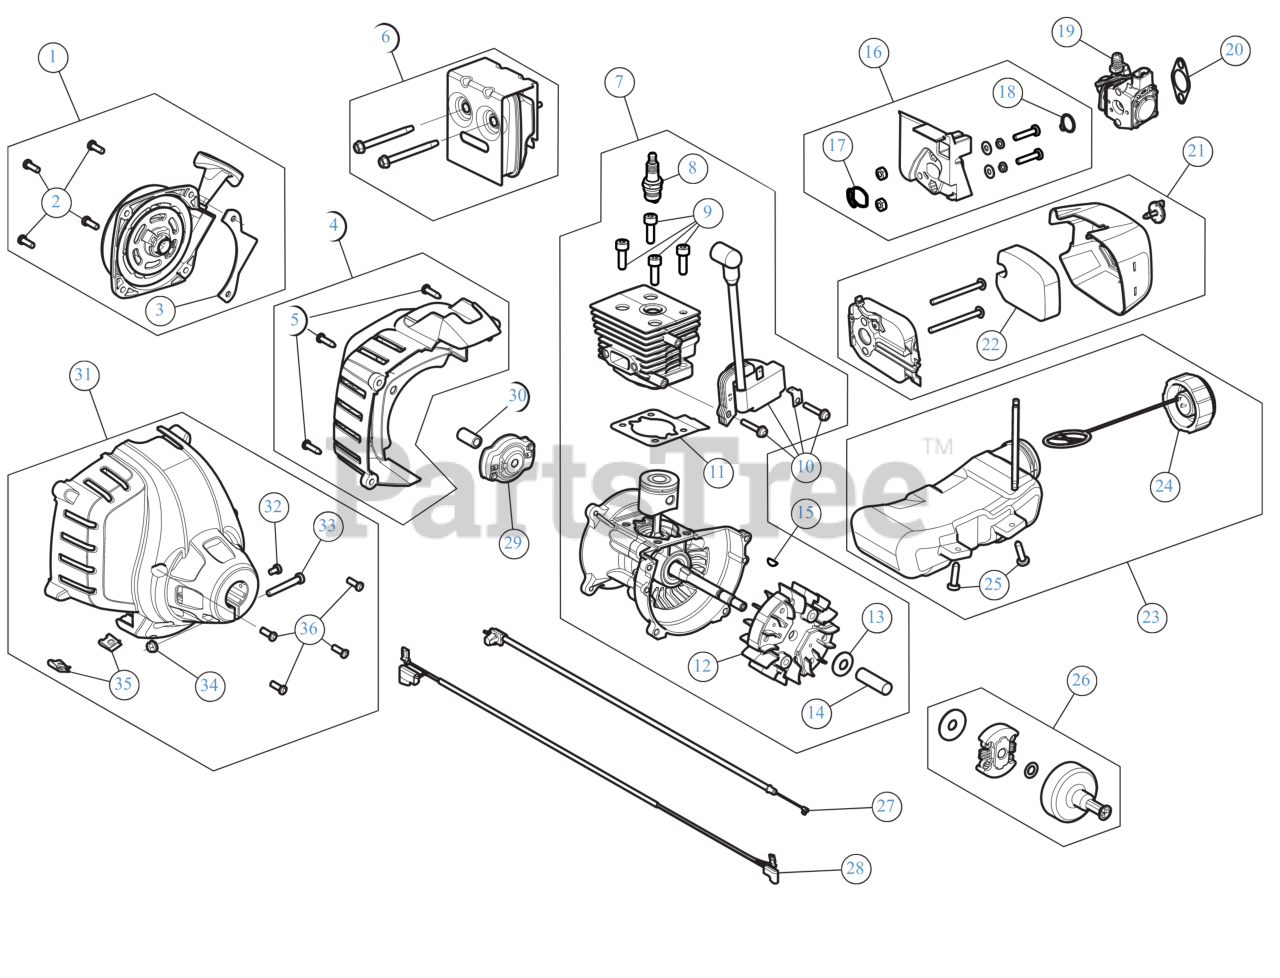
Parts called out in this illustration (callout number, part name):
1	STARTER ASSEMBLY
2	SCREW:10-32X.562:#8P
3	STARTER GUARD
4	REAR ENGINE COVER
5	SCREW, #8-16X.750 PH
6	MUFFLER ASSEMBLY
7	Short Block Assembly
8	SPARK PLUG
9	SCREW 1/4 x 20 x .8125
10	MODULE W/SLV RFI
11	GASKET CYL
12	FLYWHEEL ASSEMBLY 27CC
13	BELL WASHER
15	WOODRUFF KEY #403-.125 x .375
16	INTAKE ASSEMBLY
19	CARBURETOR
20	GASKET CARB
21	AIR CLEANER COVER
22	AIR FILTER
23	FUEL TANK ASSEMBLY
25	SCREW:10-6 x .75
26	SMALL CLUTCH ASSEMBLY W/SMALL DRUM
27	THROTTLE CABLE
28	WIRE LEAD RFI
29	PAWL ASSEMBLY AC5
30	ELECTRIC START ADP
31	CLUTCH COVER ASSEMBLY
32	SCREW, 8-32 x .312 P
35	NUT, TINNERMAN U-T
